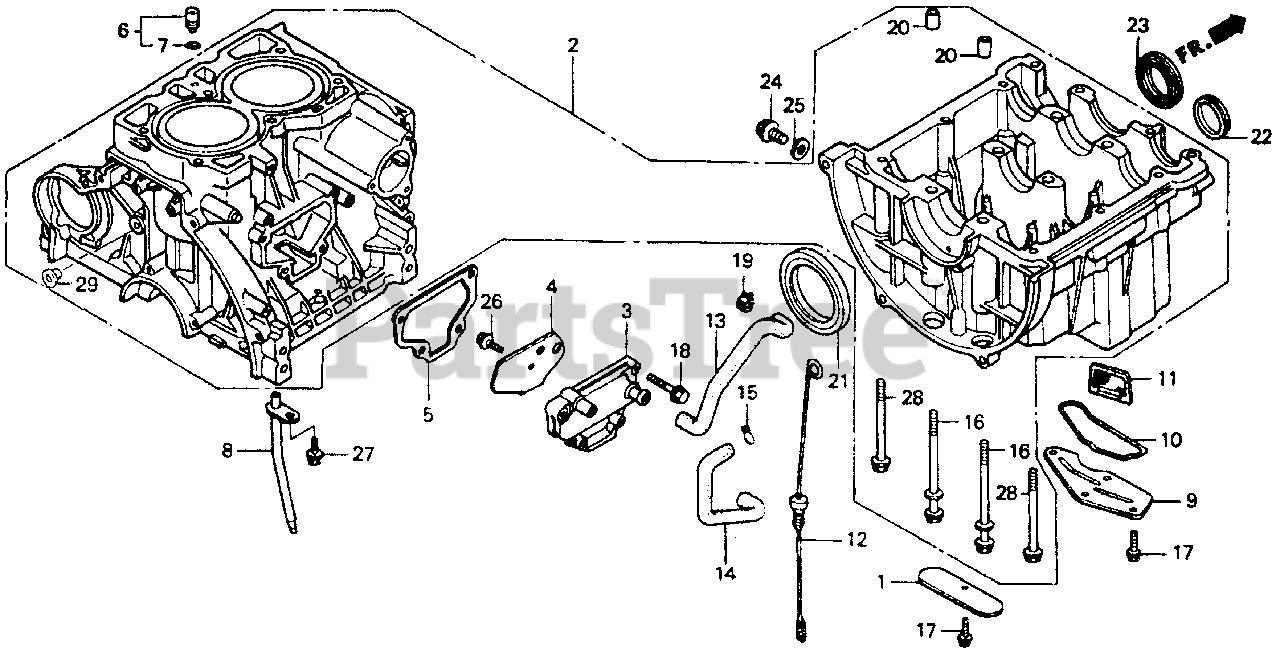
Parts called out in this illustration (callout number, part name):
1	PLATE (LOWER)
2	BLOCK ASSY., CYLINDER
3	COVER, SIDE BREATHER
4	PLATE, SIDE BREATHER
5	GASKET, SIDE BREATHER COVER
6	ORIFICE ASSY., OIL PASSAGE
7	O-RING (4.8X1.9)
8	PIPE, BREATHER
9	PLATE, OIL FILTER
10	O-RING, OIL PLATE
11	SCREEN, OIL FILTER
12	DIPSTICK, OIL
13	TUBE A, BREATHER
14	TUBE B, BREATHER
15	CLIP, BREATHER TUBE
16	BOLT-WASHER (10X105)
17	BOLT, FLANGE (6X14)
18	BOLT, FLANGE (6X32)
19	CLAMP, CANISTER HOSE
20	PIN, DOWEL (13X20)
21	OIL SEAL (65X88X12)
22	PLUG, SEALING (42X7)
23	OIL SEAL (35X50X8)
24	BOLT, DRAIN PLUG (12MM)
25	WASHER, DRAIN PLUG (12MM)
26	BOLT, FLANGE (6X12)
27	BOLT, FLANGE (6X14)
28	BOLT, FLANGE (8X85)
29	BOLT, SEALING
